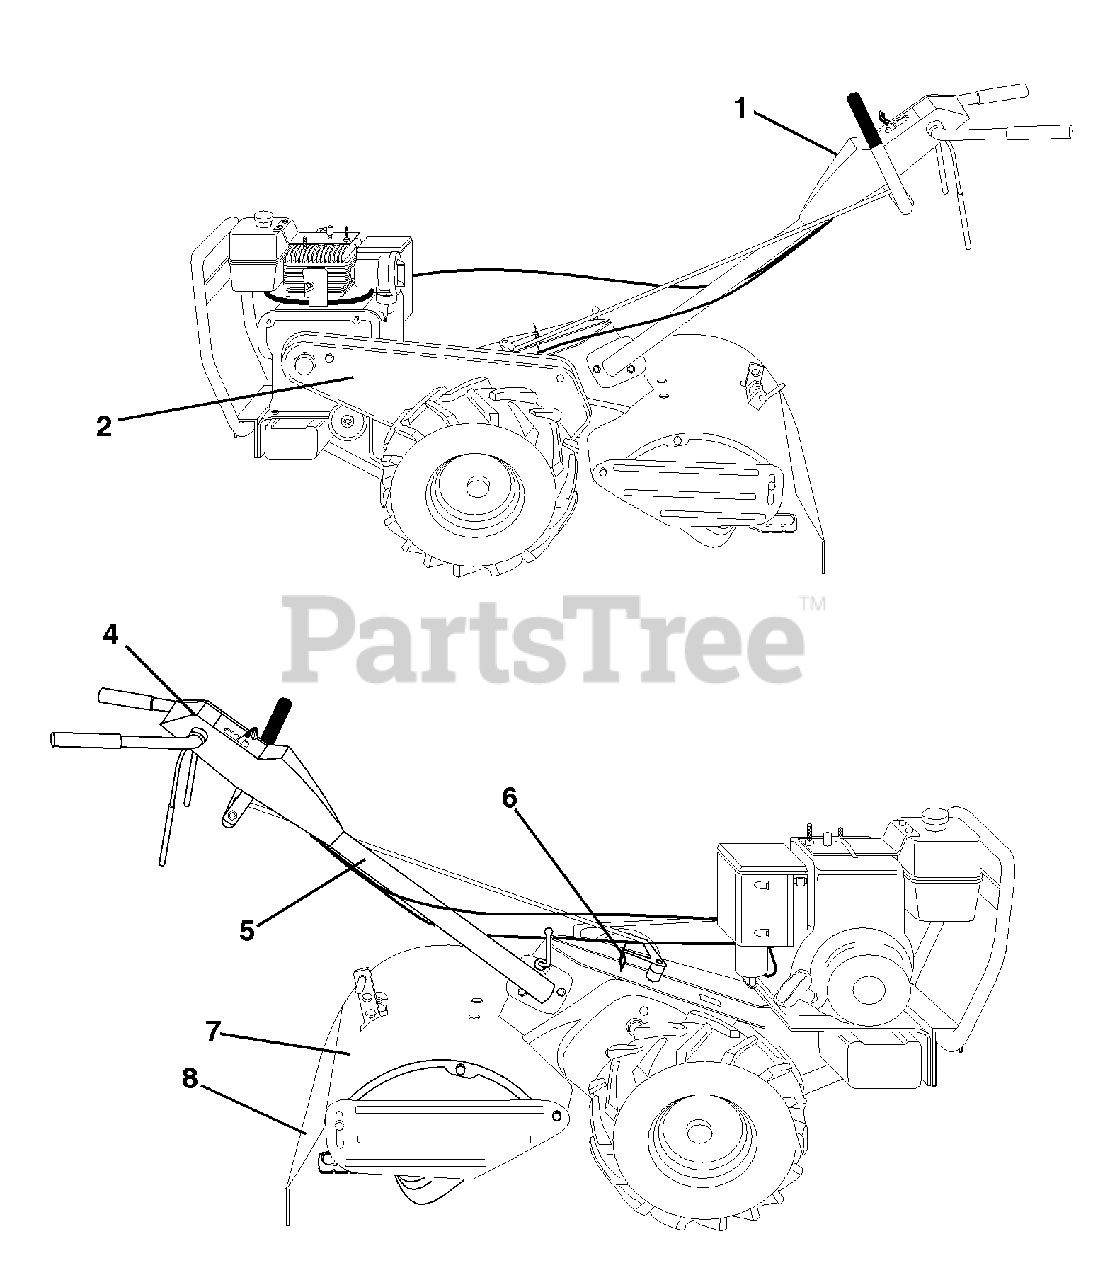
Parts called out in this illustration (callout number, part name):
1	Decal, Logo
2	Decal, Logo
4	Decal, Instruction, Tilling
5	Decal, Hand Placement
6	Decal, Shift Indicator
7	Decal, Caution
8	Decal, Warning, Rotating Tines
